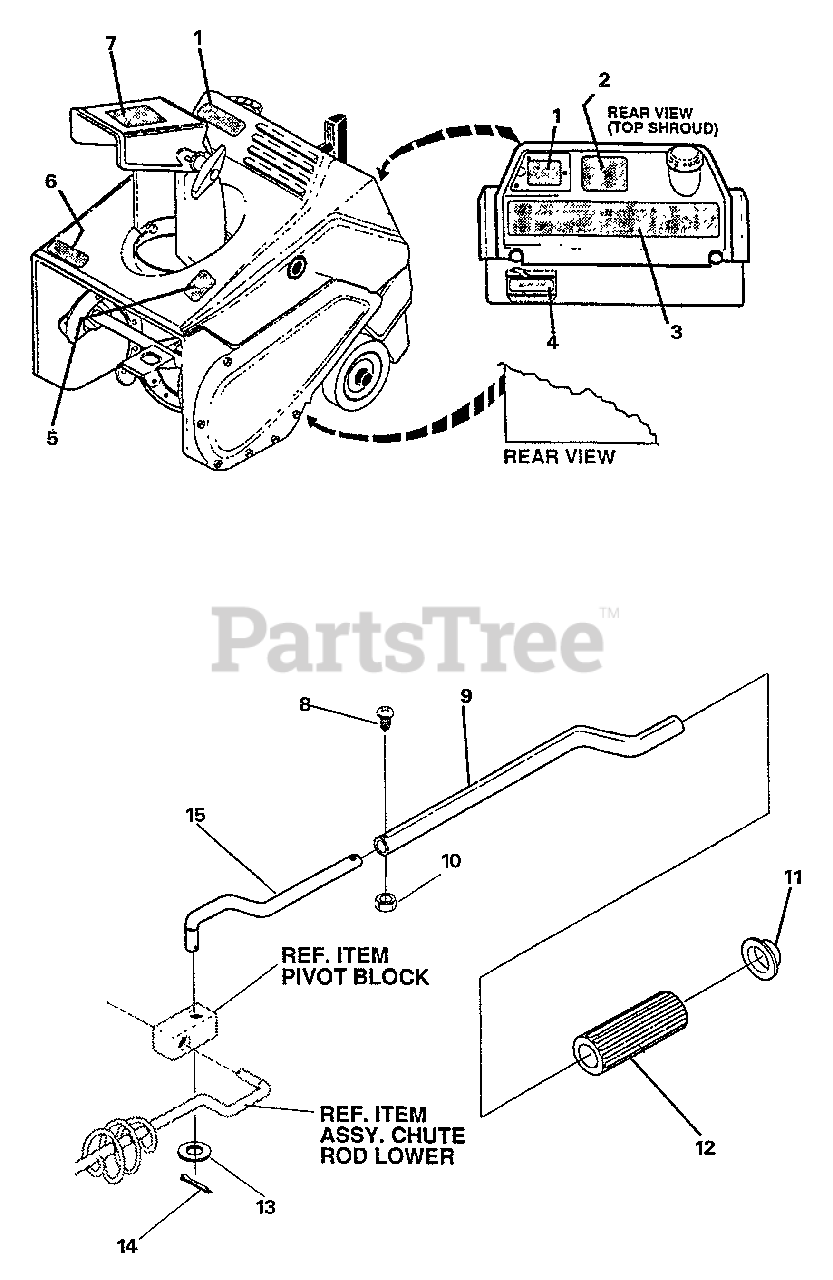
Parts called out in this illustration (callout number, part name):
1	LABEL - ECHO -- ST-5000E
2	LABEL - STARTING
3	LABEL - CONTROL PANEL
4	LABEL - CHOKE
5	LABEL - DANGER
6	LABEL - ECHO
7	LABEL - DANGER
8	SCREW - 10-32 X 7/8"
9	ROD, UPPER CHUTE CONTROL
10	LOCKNUT - 10-32
11	NUT - PUSH -- 3/8
12	KNOB, CHUTE, CRANK
13	WASHER - .40 X .75 X .025"
14	PIN, SPLIT
15	ROD, CHUTE CONTROL MIDDLE
